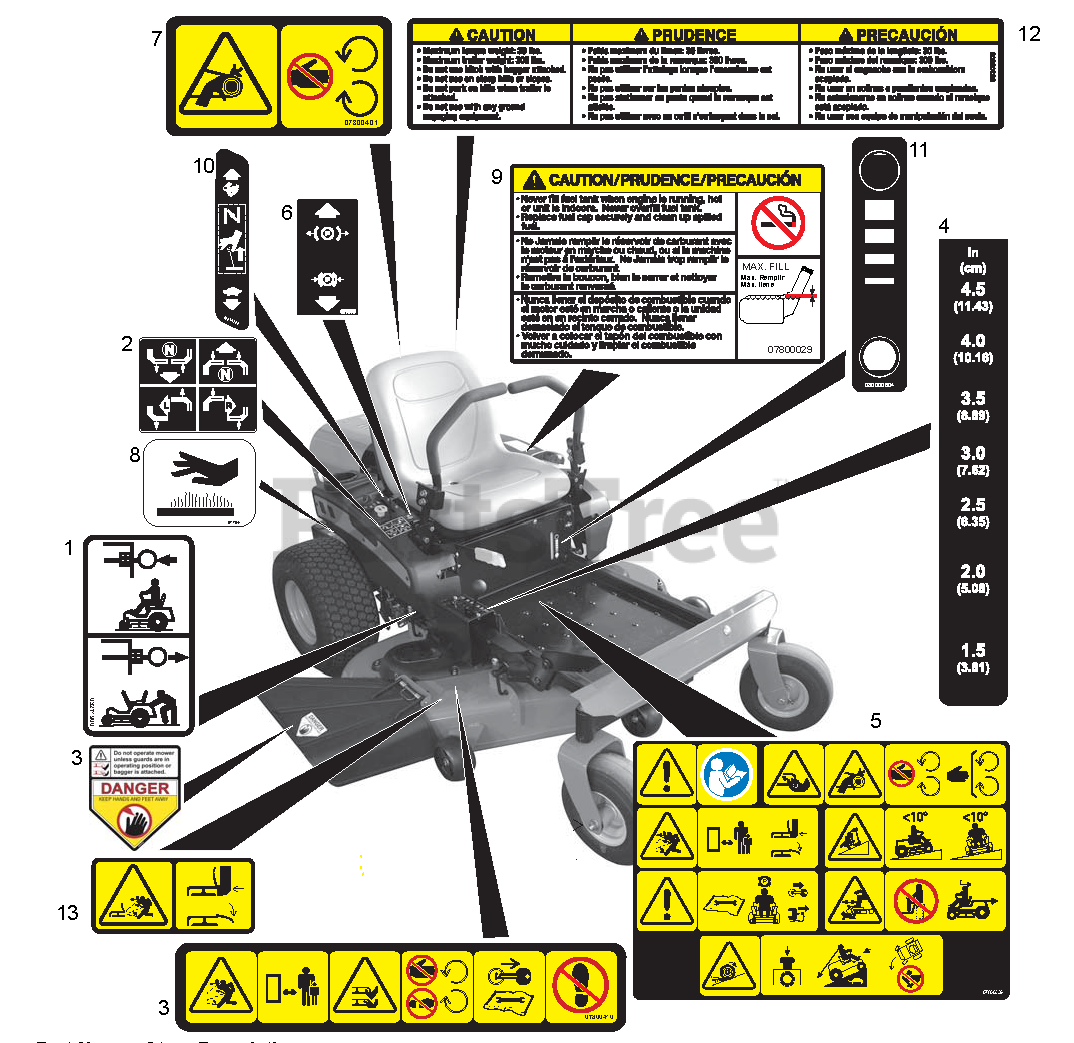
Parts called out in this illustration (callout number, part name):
1	DECAL, TRANSMISSION DISCONNECT
2	DECAL, INSTRUCTIONAL-STEERING
3	DECAL, DECK SAFETY
4	DECAL, HEIGHT OF CUT
5	DECAL, SAFETY - MAIN
6	DECAL, PARKING BRAKE LEVER
7	DECAL, SAFETY - GUARDING
8	DECAL, HOT SURFACE
9	DECAL-FUEL, WARNING
10	DECAL, SPEED CONTROL
10	DECAL, THROTTLE/CHOKE COMBO
11	DECAL, FUEL LEVEL
12	DECAL, TRAILER HITCH
13	DECAL, SAFETY - DECK GUARDING
